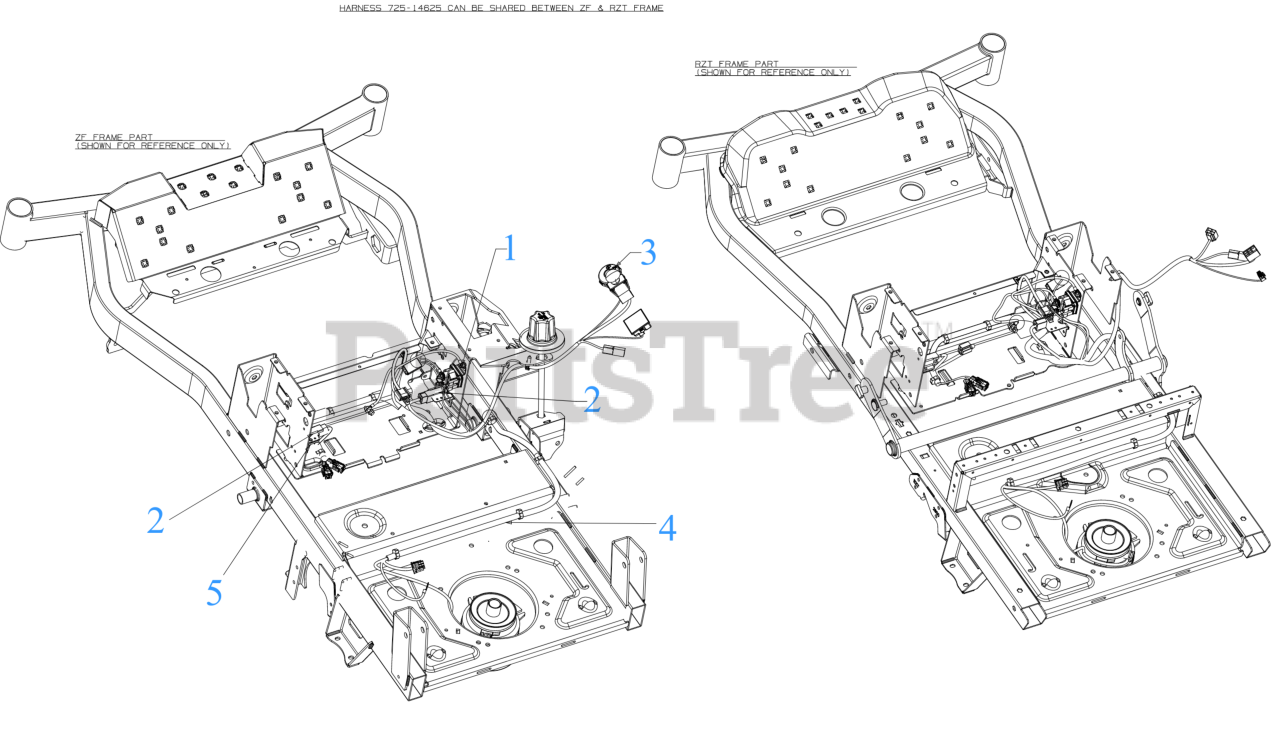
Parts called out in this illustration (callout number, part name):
1	SCREW 1/4-20X.625
2	INTERLOCK SWITCH (NO/NC)
3	KEY SWITCH (3 POS 6 PIN)
4	MAIN HARNESS
4	12V SOLENOID
5	SHOULDER SCREW
